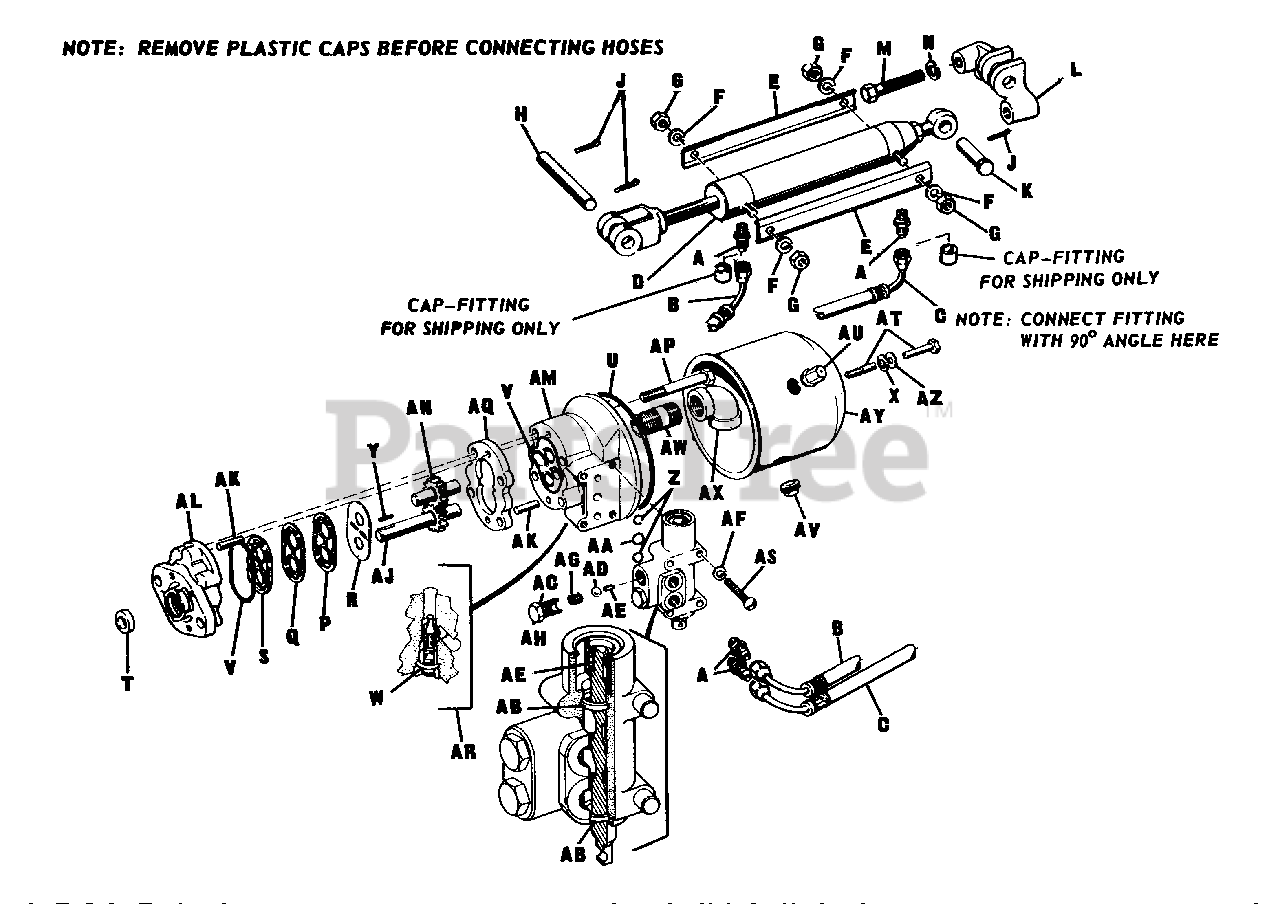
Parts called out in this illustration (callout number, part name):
B	Hose Assembly
C	Hose Assembly
D	Cylinder Assembly
F	Lock Washer, 5/16"
G	Full Hex. Nut, 5/16"-18
J	Cotter Pin, 1/8" x 3/4"
K	Ram Bracket Pin
L	Ram Bracket
M	Hex. Cap Screw 7/16"-14 x 2-1/4"
N	Lock Washer, 7/16"
P	Heat Shield (for service only)
R	Wear Plate
T	Rotary Seal
X	Stat-O-Seal
Y	Shaft Drive Key
AF	Lock Washer 1/4"
AJ	Drive Gear Assembly
AK	Dowel Pin
AL	Front Cover Assembly
AM	Back Cover Assembly
AN	Driven Gear Assembly
AQ	Center, Section Machined
AR	Relief Valve Assembly
AU	Filler Cap Plug
AV	Drain Plug
AW	Inlet Nipple
AX	Inlet Elbow
AY	Tank Assembly
AZ	Flat Washer, 1/4"
